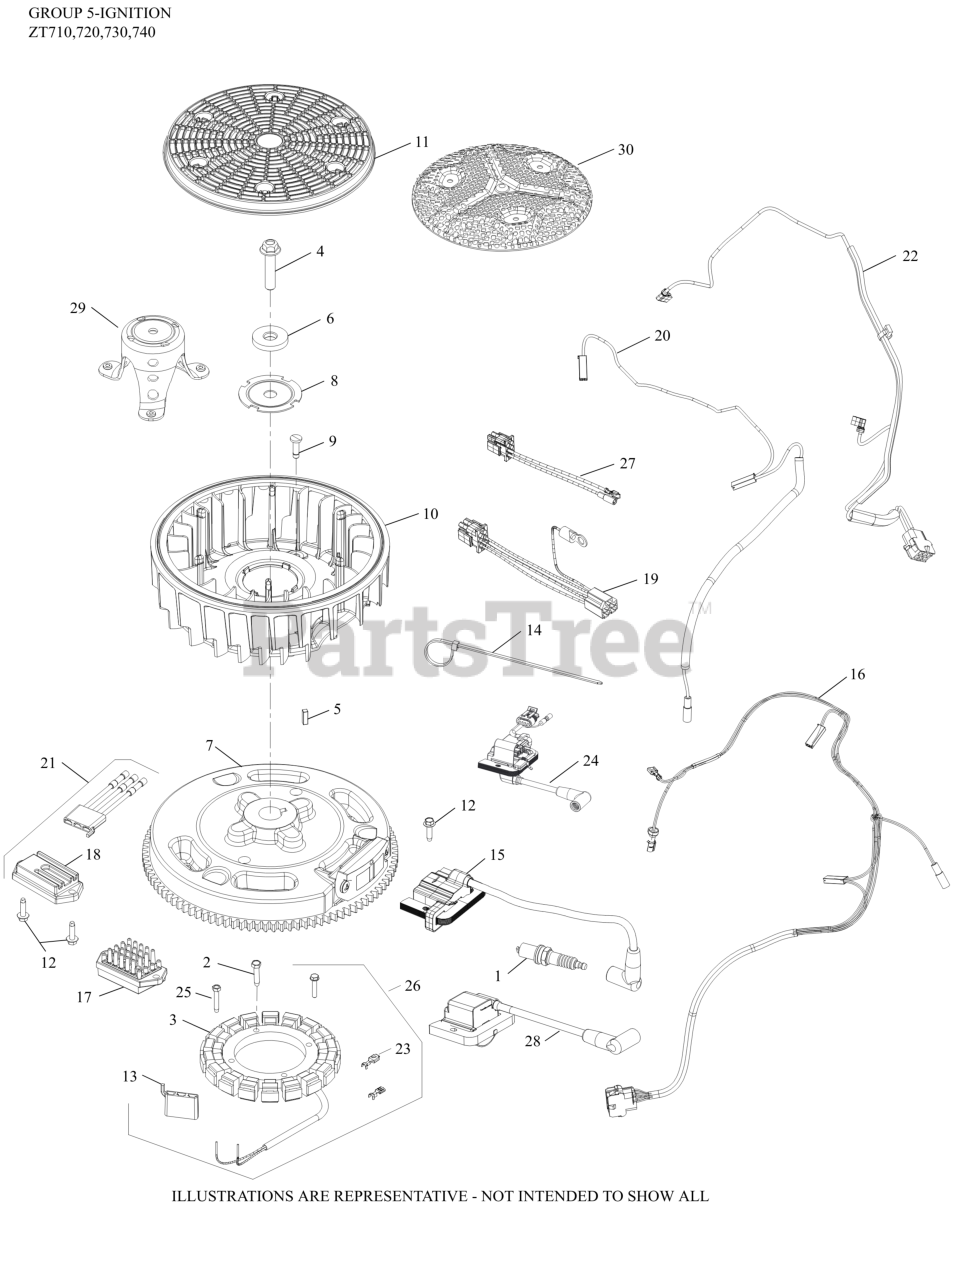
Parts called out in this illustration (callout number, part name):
1	PLUG, SPARK
2	SCREW, THREAD FORMING
3	KIT, 15 / 20 AMP STATOR
4	SCREW, HEX FLANGE
5	KEY, SQUARE
6	WASHER, FLAT
7	FLYWHEEL ASSEMBLY
9	RETAINER, FLYWHEEL FAN
12	SCREW, THD FRM-USE 25 086 473-S
13	CONNECTOR
15	MODULE, MDI IGNITION-USE 32 584 24-S
16	HARNESS, WIRING ASSEMBLY
17	REGULATOR/RECTIFIER 12/15A HALF-WAVE STD
